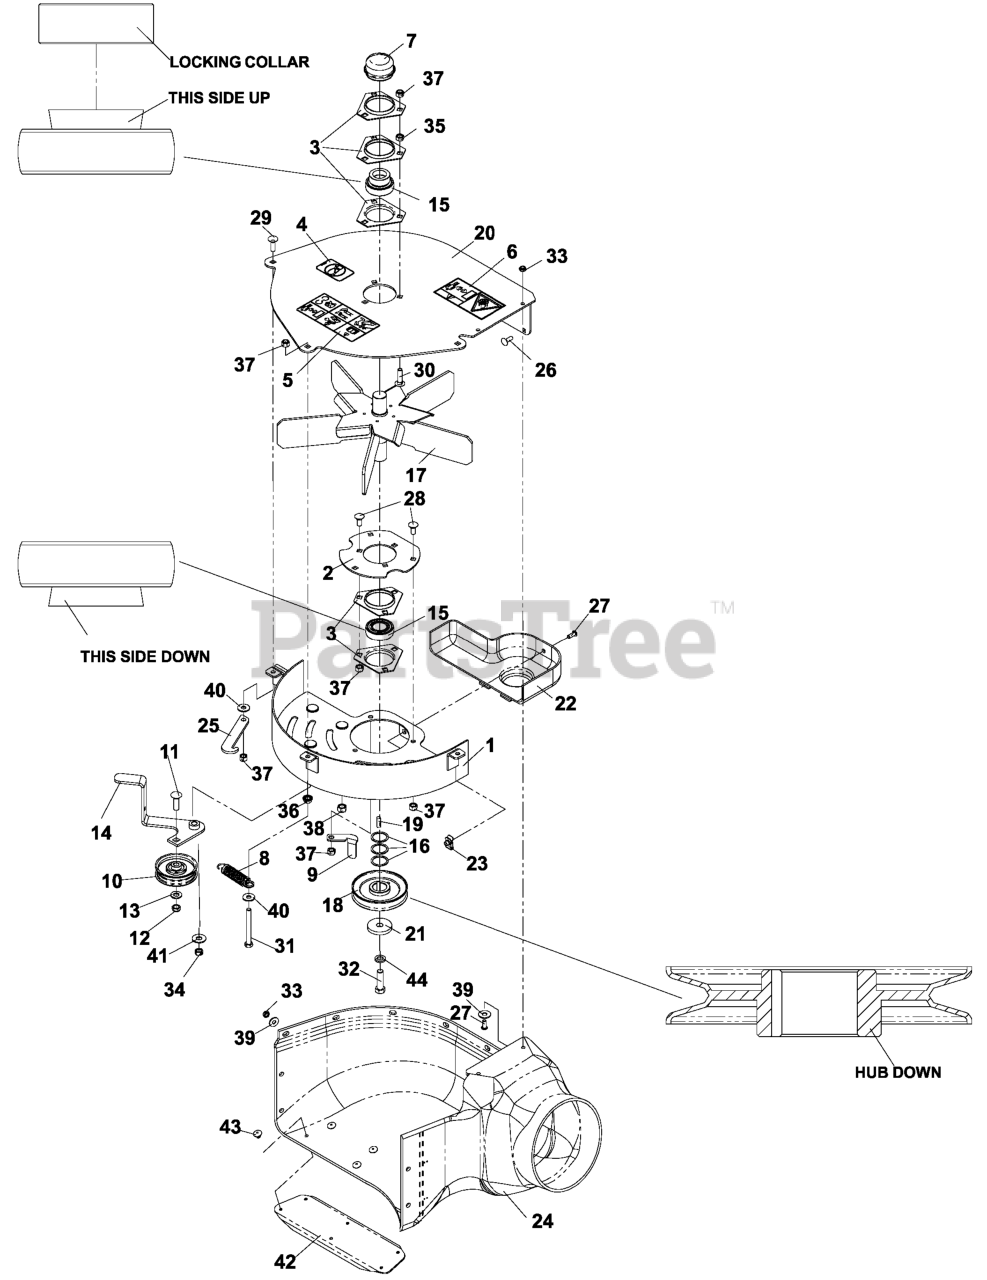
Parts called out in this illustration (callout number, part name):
1	FLOOR WELDMENT
2	BEARING PLATE
3	BRG FLANGE
4	DECAL, NO STEP
5	DECAL, EURO WARNING
6	EURO DECAL, IMPELLER
7	GREASE CAP
8	SPRING-TRANS
9	BELT GUIDE
11	RHSNB 3/8-16 X 1-1/4
12	NUT HEX 3/8-16 NYLON, THIN
13	WASHER 3/8 SAE FLAT
15	BEARING KIT-2 PCS
16	BUSHING.MACHINE.18.GAUGE
17	SPINDLE BLOWER FAN
19	KEY 1/4 SQ X 3/4
20	FAN COVER W/DECALS
21	SPINDLE WASHER
22	PULLEY SHEILD
23	1/4C - U TYPE RETAINER
24	BLOWER HOUSING
25	KEEPER, IDLER
26	RHSNB 1/4C X 3/4
27	SCR 1/4-20 X 5/8 BTN SKT HD ZD
28	RHSNB, 5/16 X 3/4
29	RHSNB 5/16C X 1
30	BOLT, CARRIAGE 5/16X1-1/4
31	HCS 5/16C X 2-3/4
32	HCS 7/16F X 1 1/2
33	JAM NUT 1/4C (2 2 PW01)
34	NUT, 5/16C, CENTERLOCK
35	NUT 5/16C HEX
36	NUT 5/16C WHIZ
37	NUT 5/16 NYLOC
38	NUT 3/8-16 NYLOC
39	WASHER 1/4 FLAT
40	WASHER 5/16 FLAT
41	WASHER 3/8 FLAT
42	BLOWER SUPPORT
43	RIVET E/16 X 1/4 LG FLG
44	WASHER 7/16 LOCK
